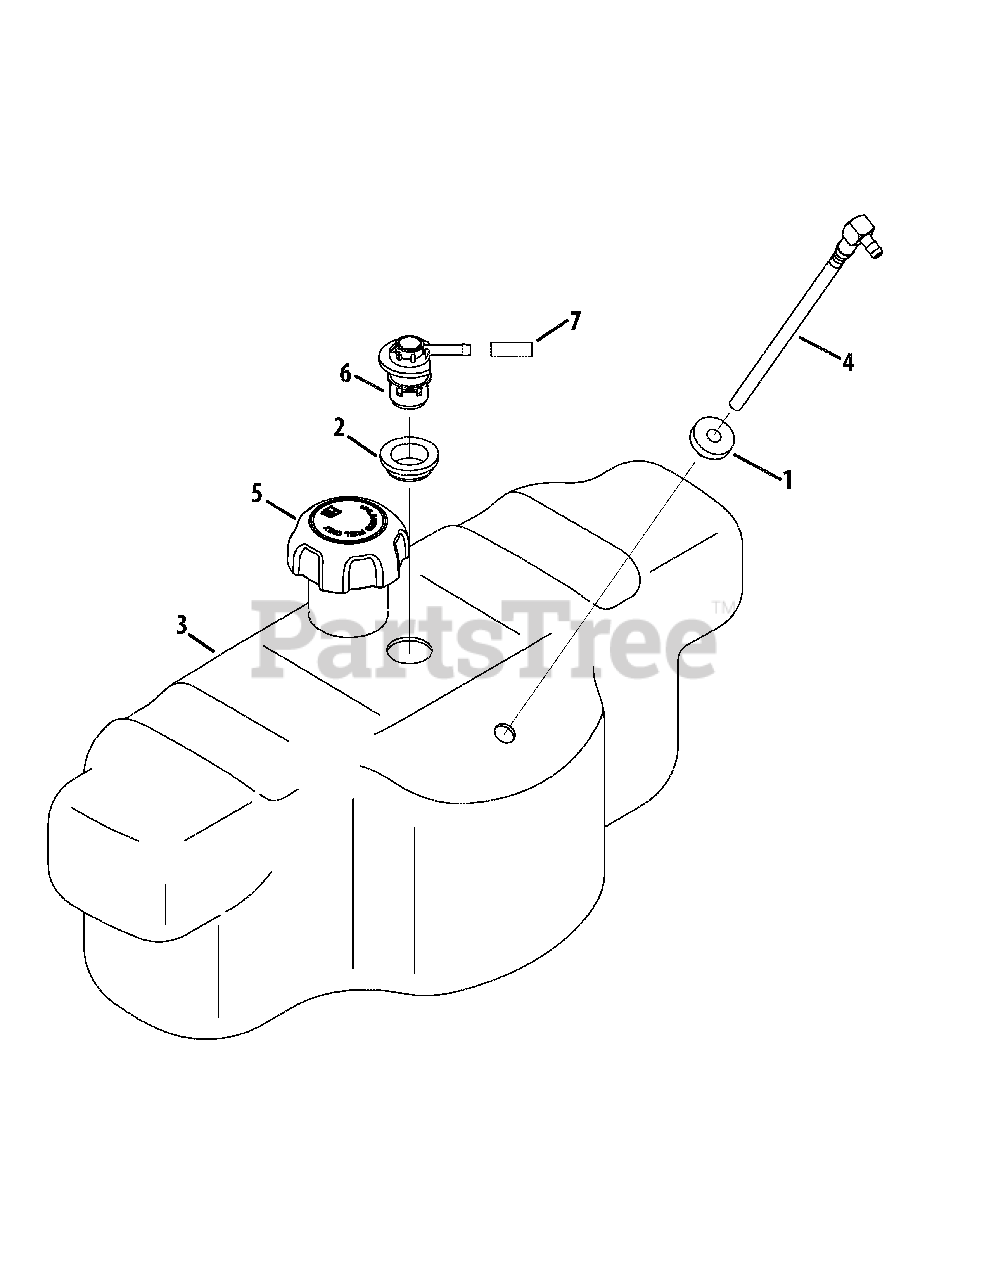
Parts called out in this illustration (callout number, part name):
1	Fuel Tank Bushing
2	Rubber Grommet
3	Fuel Tank Assembly
4	Fuel Pick-Up Fitting
5	Fuel Cap
6	Fuel Rollover Valve
7	Vent Hose
